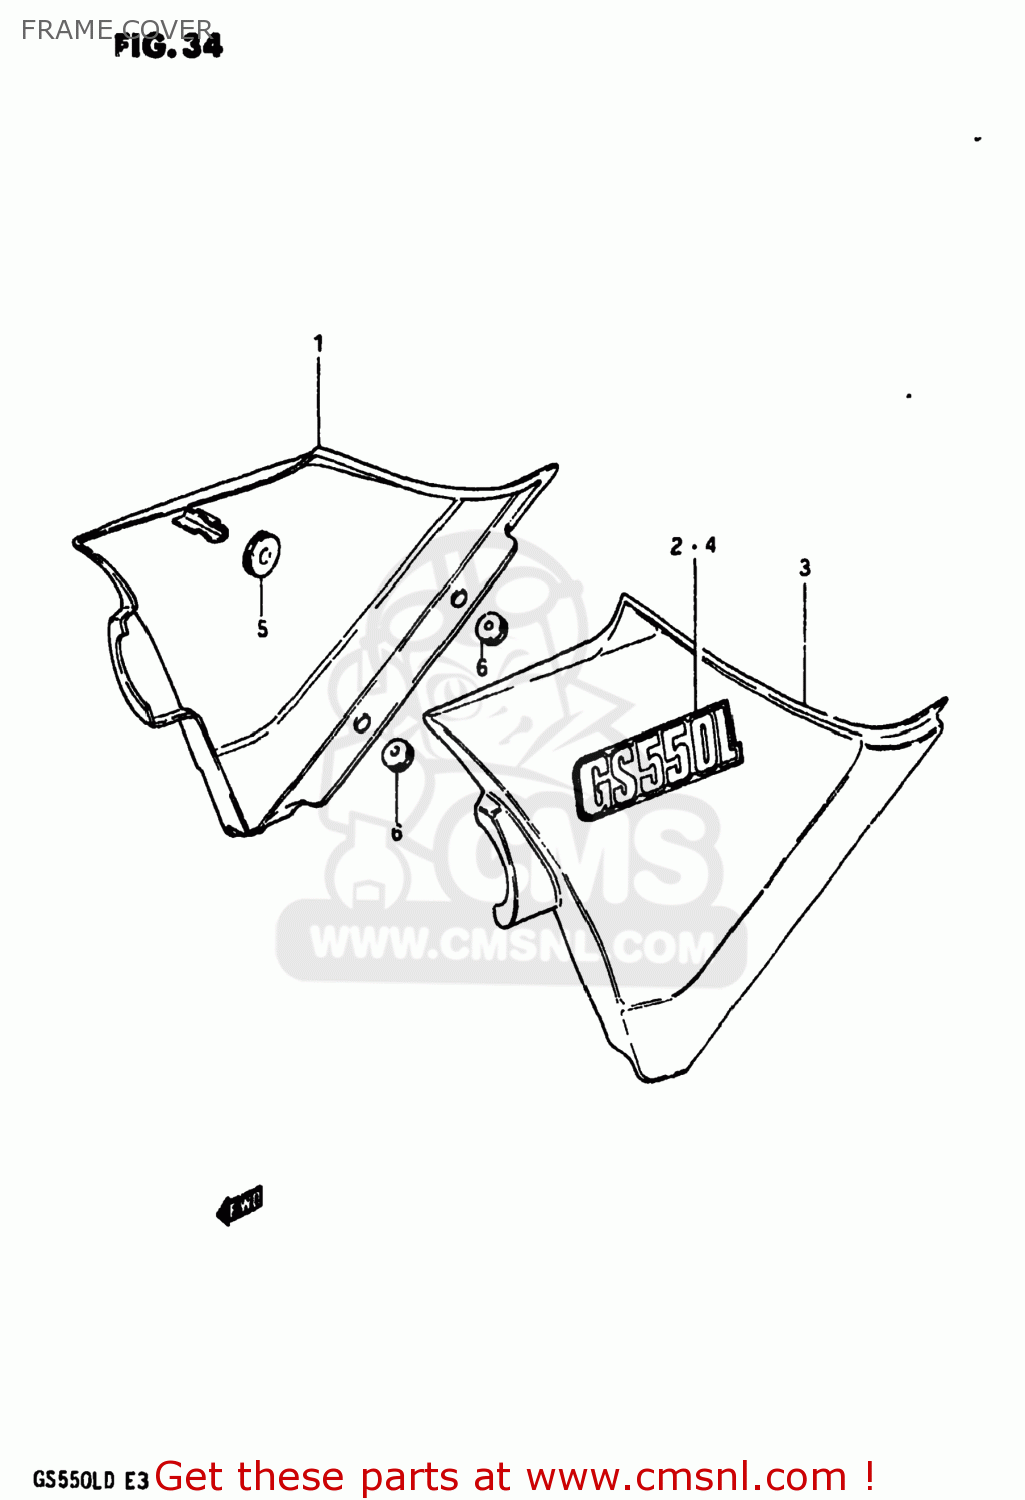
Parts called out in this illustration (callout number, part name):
1	COVER,FRAME,RIGHT
2	EMBLEM,FRAME COVER
3	COVER,FRAME,LEFT
4	EMBLEM,FRAME COVER
5	CUSHION
6	CUSHION
